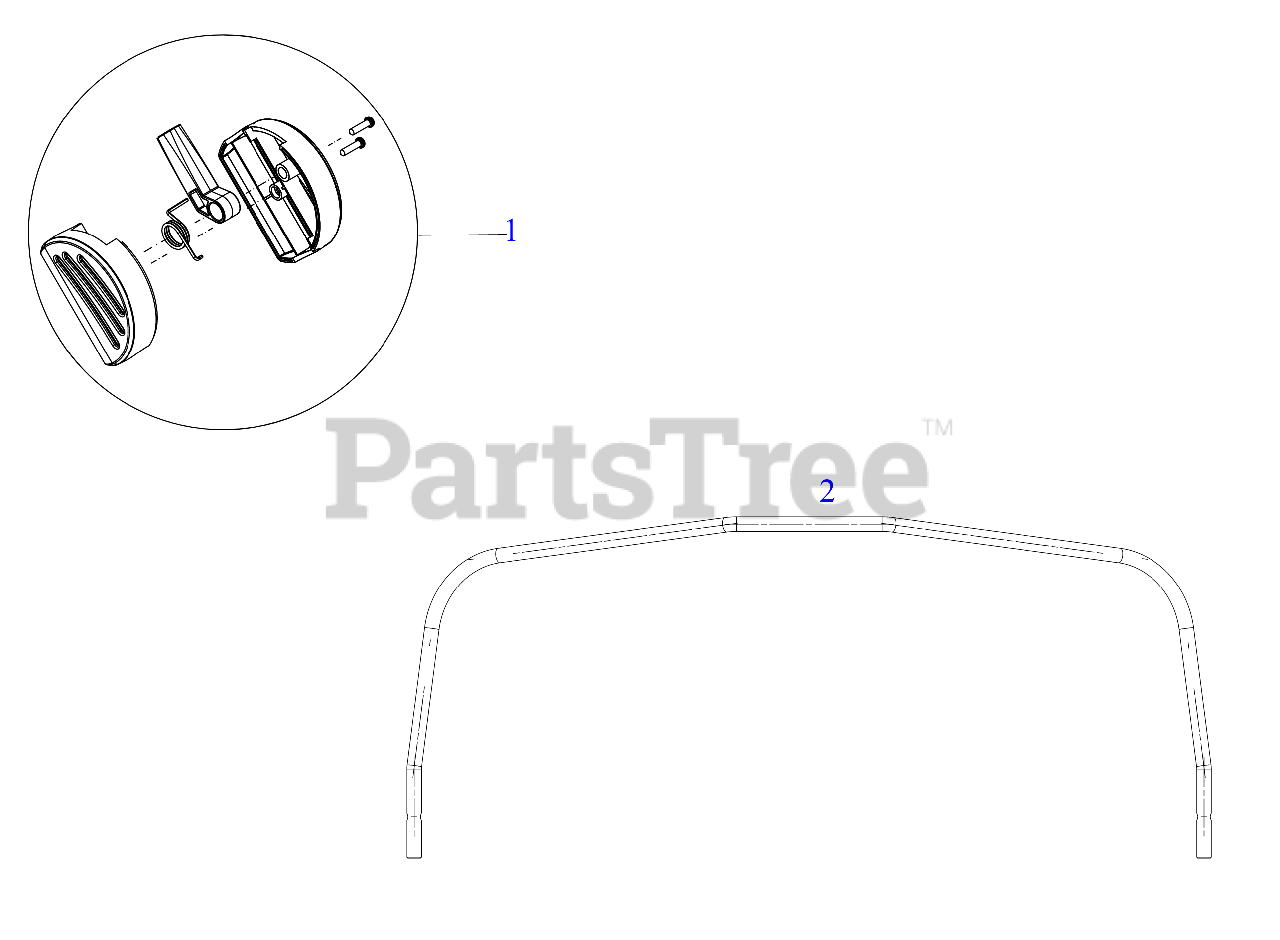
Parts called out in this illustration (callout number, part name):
1	BAIL HOUSING ASSEMBLY (LH)
3	SCREW TT #8-32 x .375" T20
4	SCREW TAP HL #8-18 x .63
